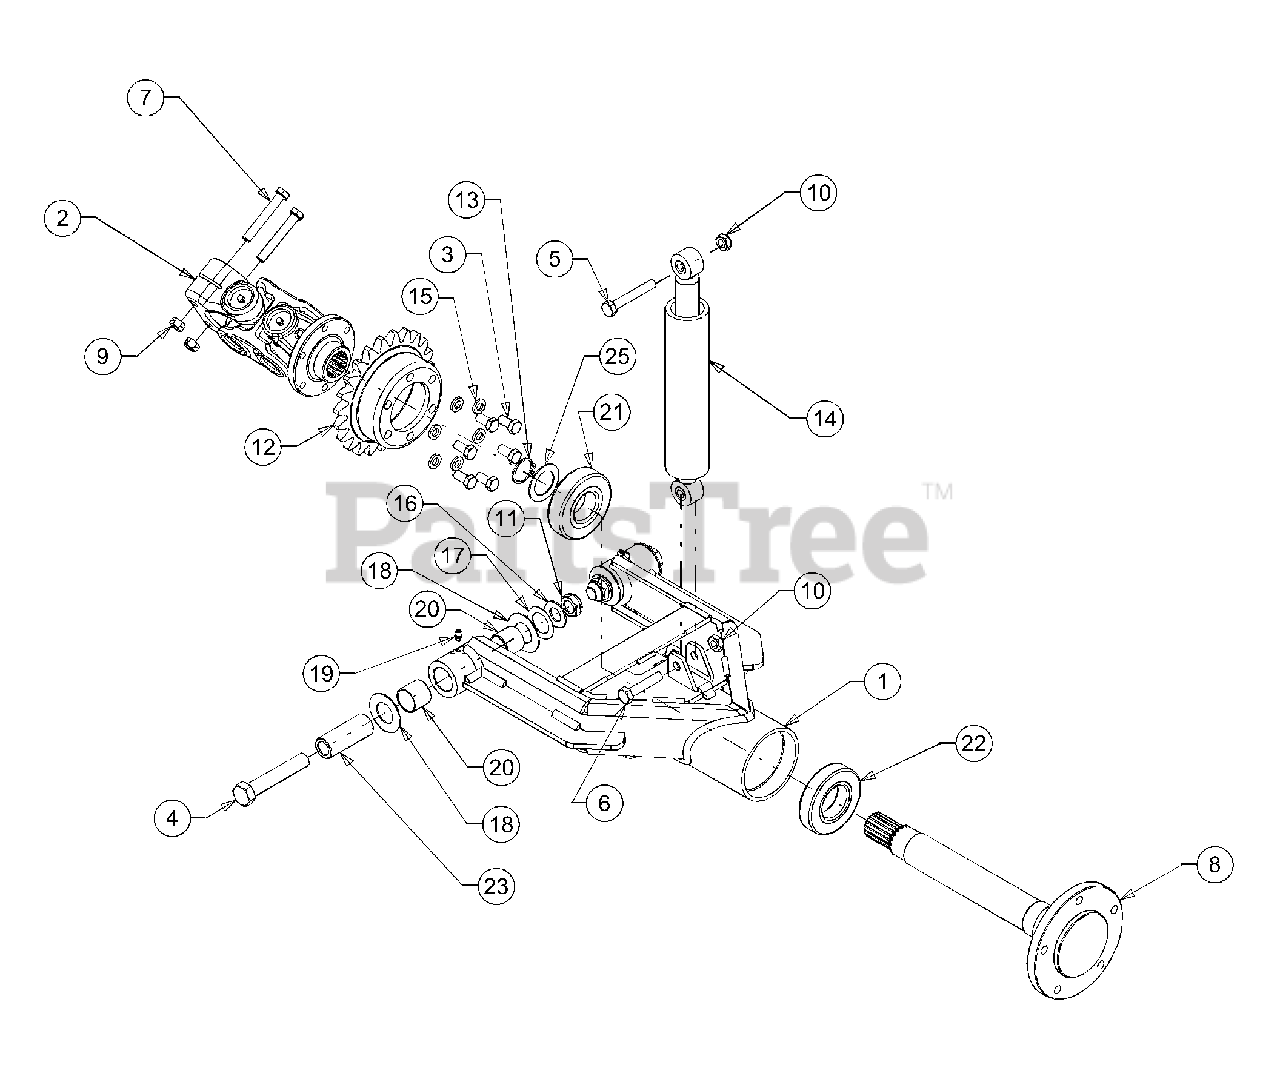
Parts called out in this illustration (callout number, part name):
2	Weld Coupling Assembly
3	Screw, Hex, 3/8-16 x .75, Gr5
4	Screw, Hex, 5/8-18 x 3.5, Gr5
5	Screw, M10-1.25 x .65, Gr8
6	Screw, M10-1.25 x .50, Gr8
7	Screw, Hex, 7/16-14 x 2.75, Gr5
8	Axle Shaft, Drive Center
9	Nut, Hex Lock,7/16-14
10	Nut, Nylon Lock, M10-1.25
11	Nut, Jam Lock, 5/8-18, Gr5
12	Sprocket, Hub, 1.75 - 23T
13	Retaining Ring, External, 1.14
14	Shock Absorber, 2.9 Stroke
15	Washer, Lock, 3/8 , Regular Duty
16	Washer, Flat, .65 x 1.25 x .075
17	Washer, Flat, 1.06 x 1.56 x .020
18	Washer, Flat, 1.010 x 1.86 x .060
19	Lube Fitting, 3/16
20	Bearing, 1.0 x 1.125 x 1.0
21	Ball Bearing, Internal Axle
22	Ball Bearing, External Axle
23	Spacer, .63 x 1.0 x 2.594
25	Spacer, 1.78 x 1.88
